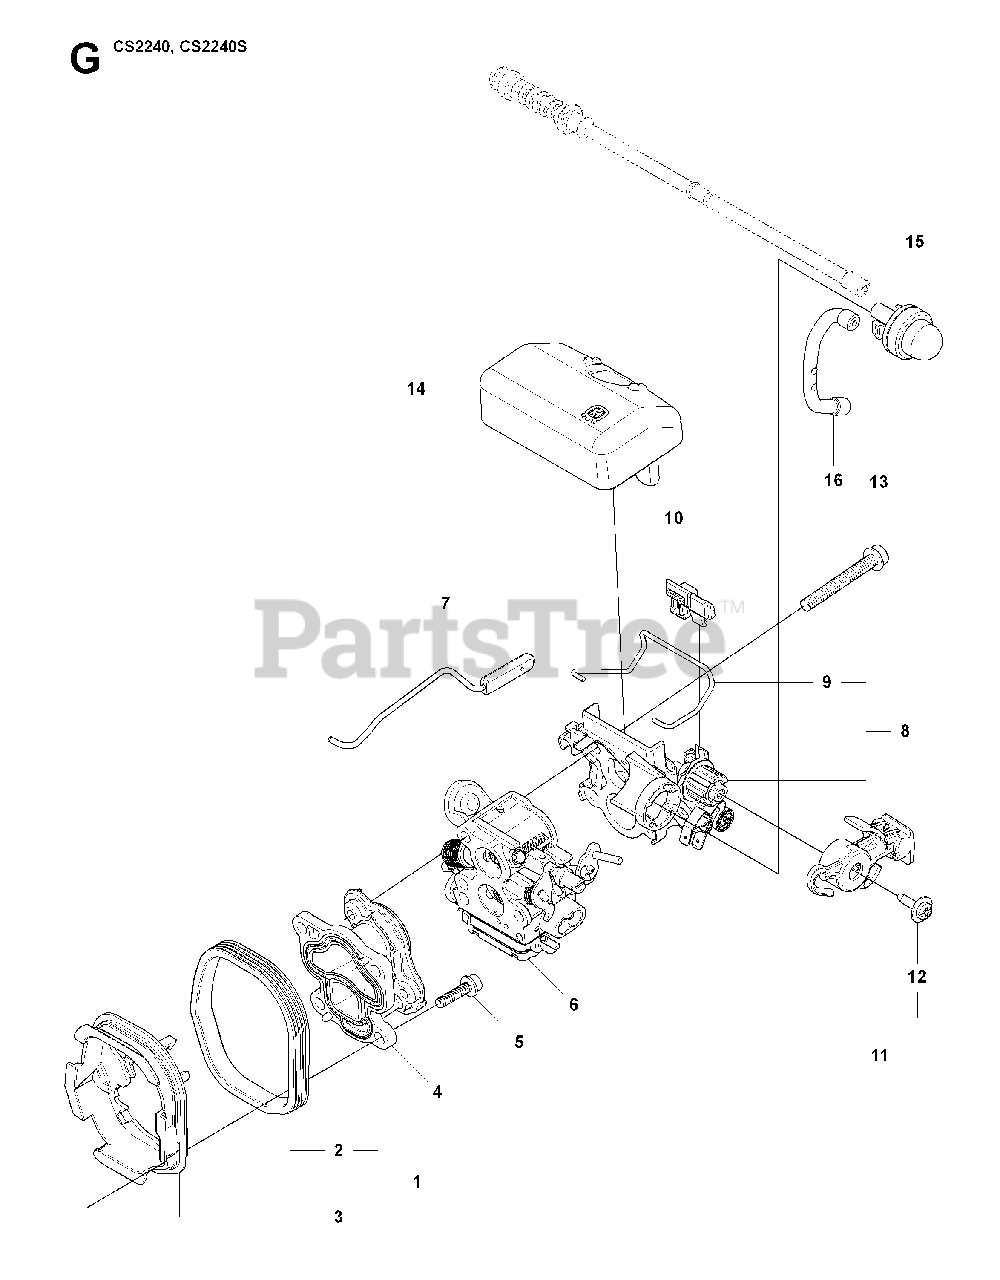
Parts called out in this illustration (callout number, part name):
1	INSULATION WALL
2	INSULATION WALL
3	INSULATION WALL
4	INLET PIPE
6	CARBURETOR
7	THROTTLE ROD ASSY
8	FILTER HOLDER
14	AIR FILTER
15	AIR PURGE BUBBLE
